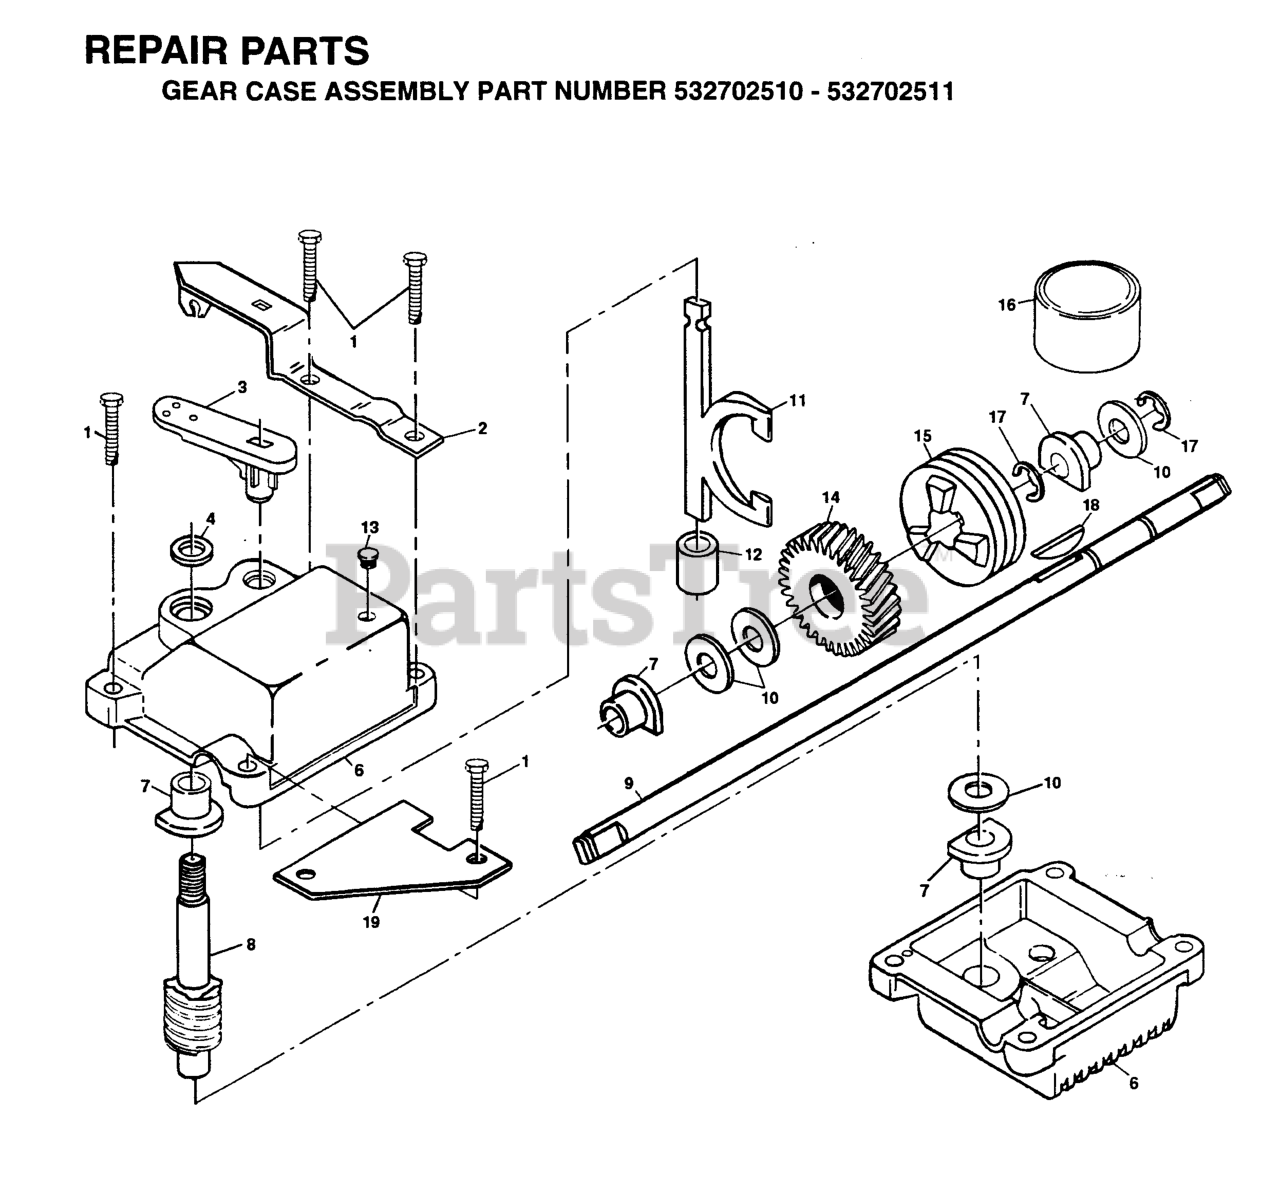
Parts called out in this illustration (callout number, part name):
1	SCREW
2	BRACKET
8	WORM SHAFT
9	DRIVE SHAFT, 20-5/8"
10	THRUST WASHER
11	YOKE.VIBRATORY FINISH.
13	PLUG.AUGER.GEAR.BOX.SNOW
14	GEAR.HELICAL
15	CLUTCH JAW
16	GREASE
18	HI PRO KEY
19	BRACKET SPRING
